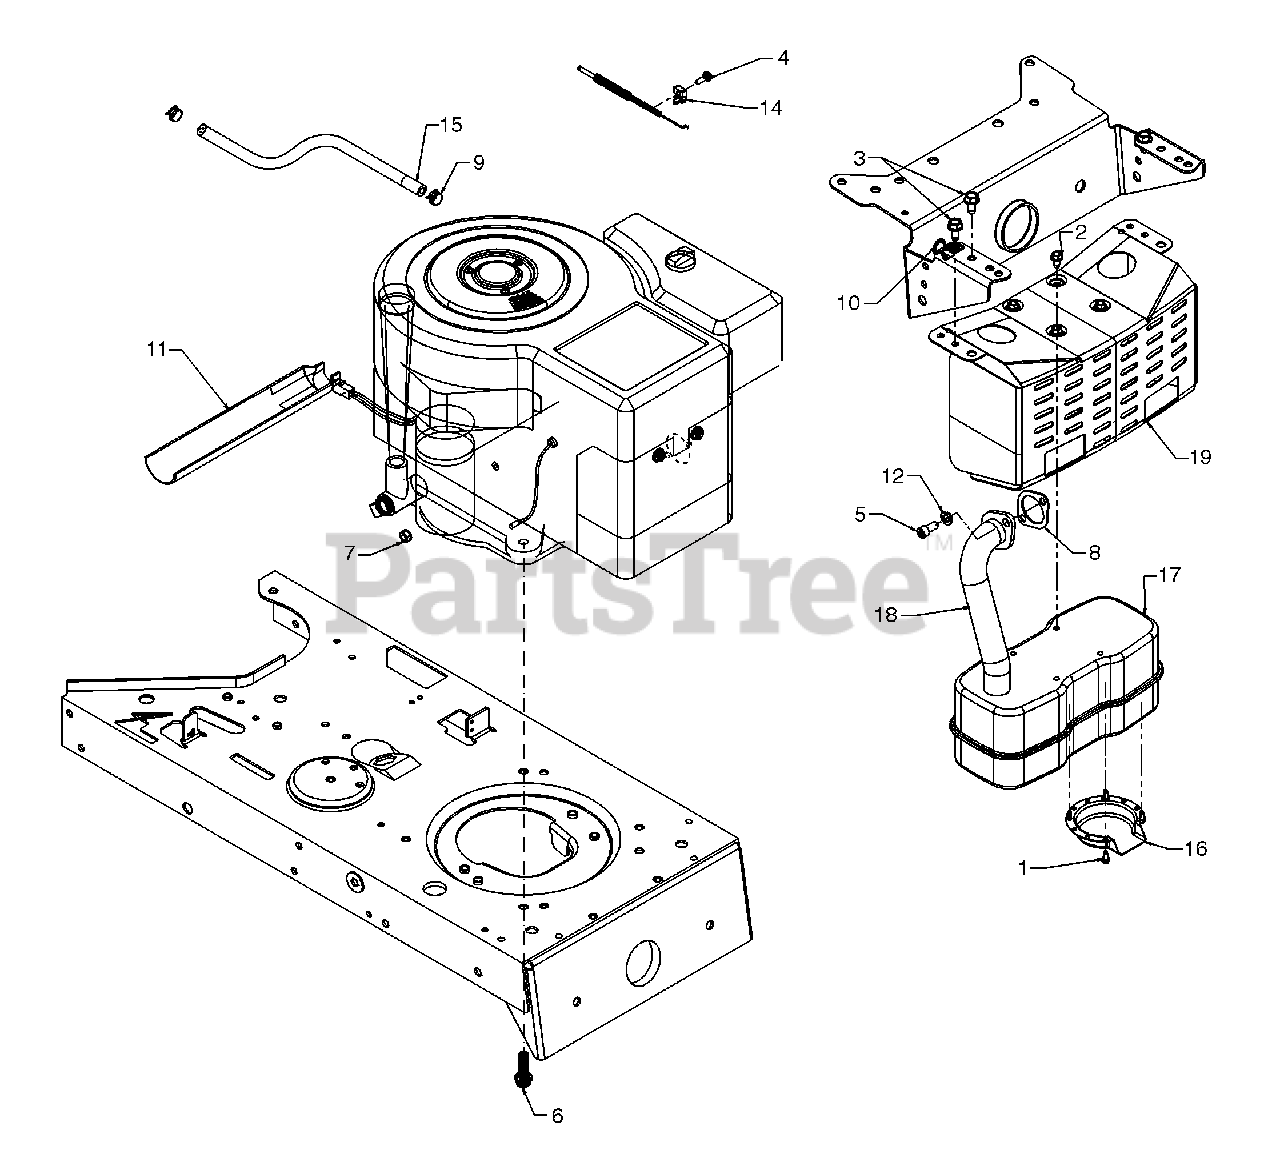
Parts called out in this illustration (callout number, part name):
1	Hex Slot Scr. #8-32 x .38" Lg.
2	Hex Washer TT-Tap Scr. 1/4-20 x .5"
3	Hex Washer TT-Tap Scr. 5/16-18 x .62"
4	Scr. #10-32: .620 Hx. Slot Wash.
5	Socket Hd. Bolt 5/16-18 x .62" Lg.
6	Scr. 3/8-16 x 1.25
7	Nut, Hex 1/4-20
8	Exhaust Gasket
9	Hose Clamp .49 Dia.
10	Clamp 9/16 Dia.
11	Oil Drain Sleeve
12	L-Wash. 5/16" 1.0.
14	Casing Clamp, Throttle, B&S
15	Fuel Line Hose
16	Muffler Deflector
17	Muffler
18	Exhaust Pipe
